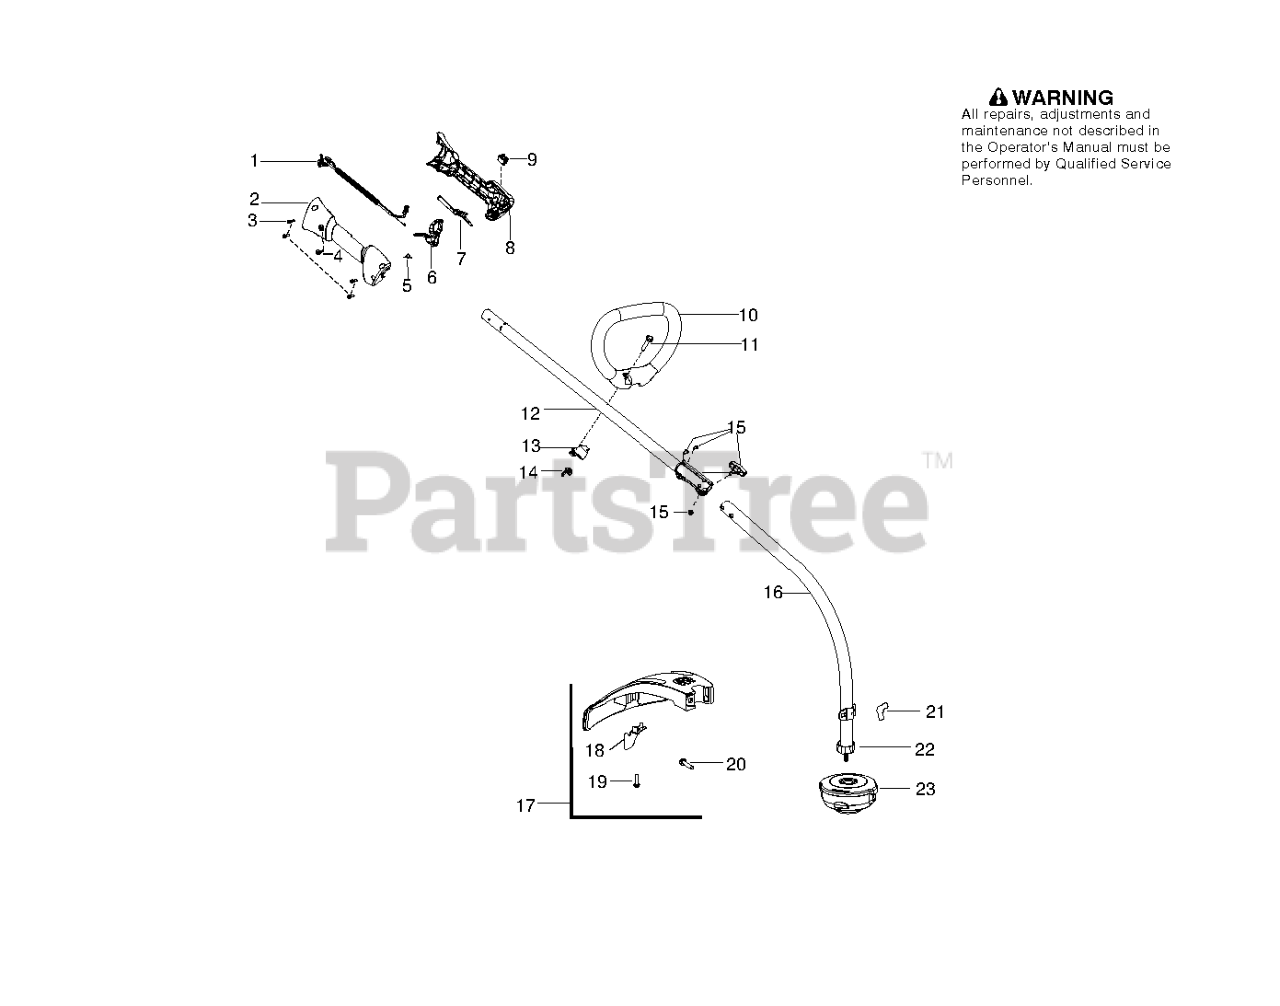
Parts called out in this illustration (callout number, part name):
1	ASSY CABLE / WIRE HARNESS
2	HSG THROTTLE RIGHT HVA
3	SCREW M4 X 1.75 PT 16MM
4	SCREW-10-14 X 1/2 PLASTITE
5	SPRING TRIGGER
6	TRIGGER THROTTLE HVA ORANGE
7	THROTTLE LOCKOUT HVA ORANGE
8	HSG THROTTLE LEFT HVA
9	SWITCH
11	BOLT, TYPE 2
12	KIT UPPER SHAFT SILVER
13	CLAMP ASSIST HANDLE
14	WINGNUT, TYPE 2
15	ASSY COUPLER BLACK
16	KIT DRIVESHAFT
17	TRIMMER GUARD 128C
20	BOLT, TYPE 2
21	WINGNUT, TYPE 2
22	DUST CUP
23	T25 TRIM HEAD RH
